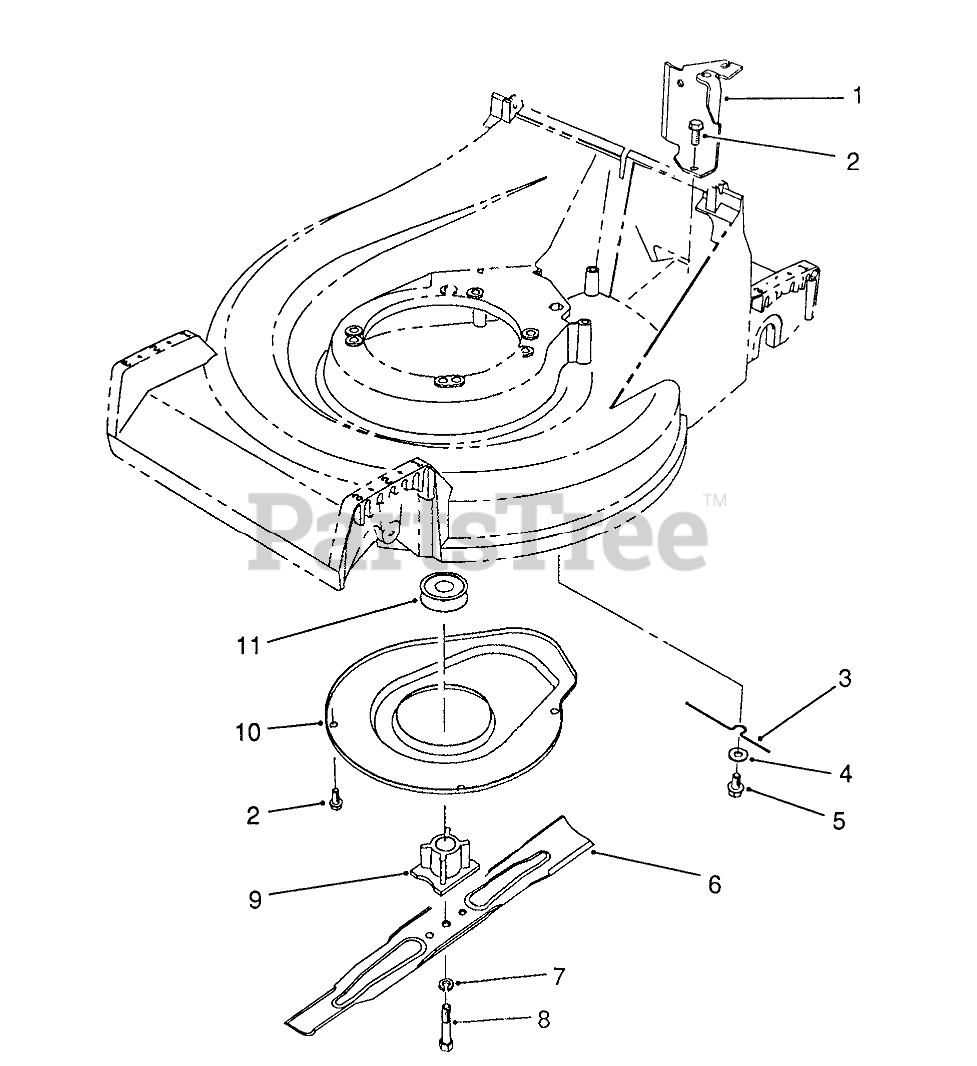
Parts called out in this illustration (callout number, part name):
1	Bracket-Cable Support
2	SCREW-HWHTF
3	RETAINER-BELT
4	WASHER-FLAT
5	SCREW-HHFTF
6	Key
7	WASHER-LOCK
8	SCREW-BLADE
9	BLADE RETAINER
10	Cover
11	PULLEY-DRIVE, ZONE START
